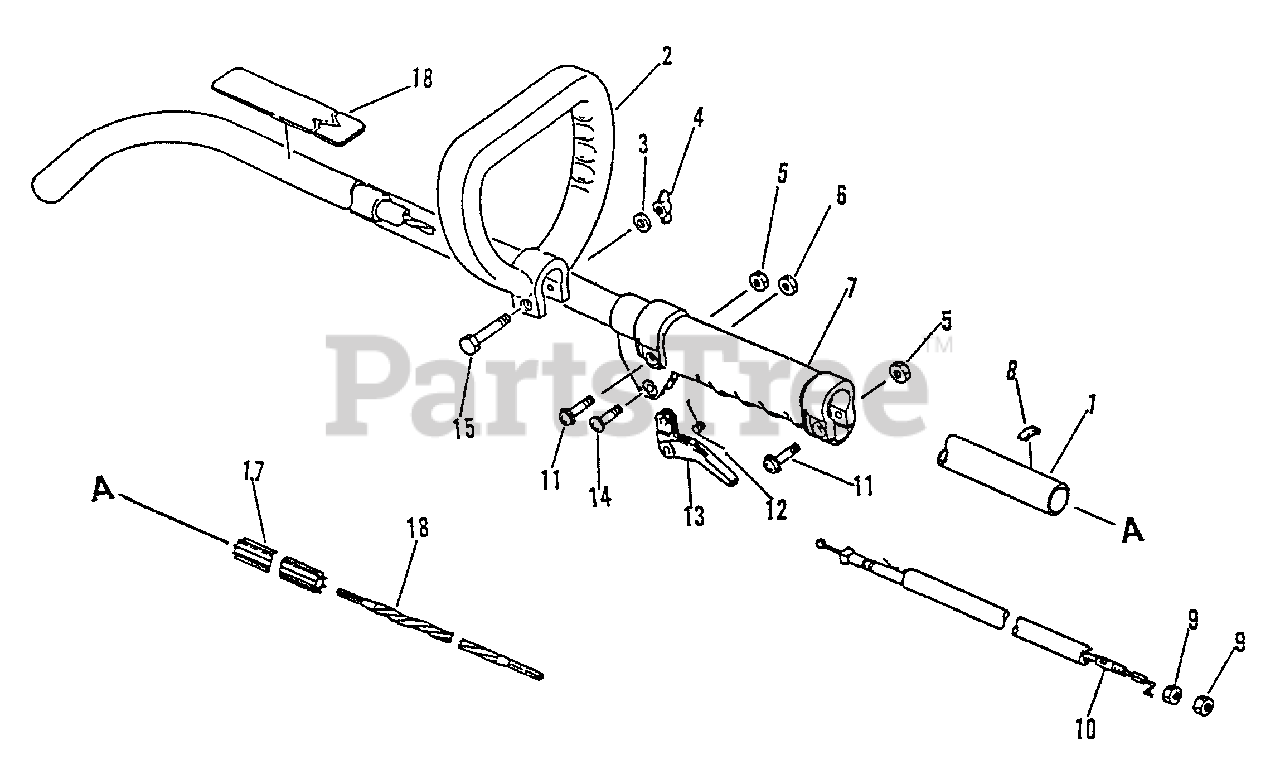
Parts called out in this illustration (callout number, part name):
1	MAIN PIPE ASSY
2	HANDLE - FRONT
3	WASHER 6.5×11.5×0.8
4	NUT, WING 6
5	NUT M5
6	NUT, LOCK M5
8	LABEL - ALIGNMENT
10	CABLE, THROTTLE
11	SCREW 5×25
12	SPRING, THROTTLE
13	TRIGGER, THROTTLE
15	BOLT - 6×40
16	DRIVESHAFT - FLEXIBLE
17	LINER - FLEXIBLE
18	LABEL - CAUTION
